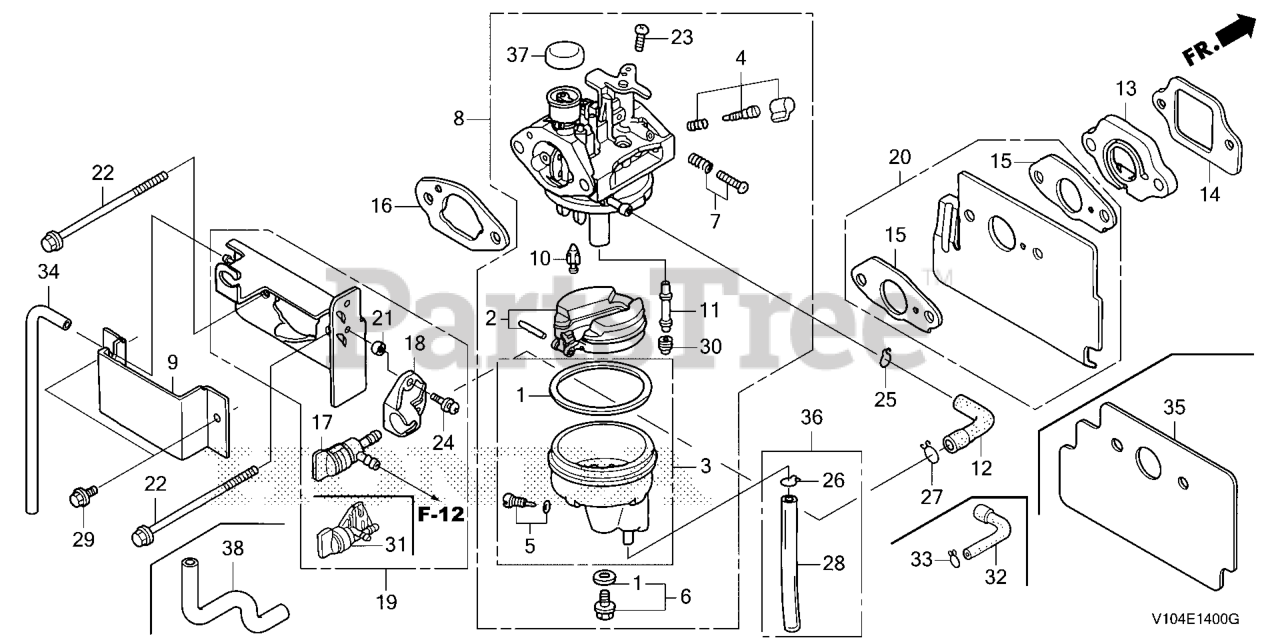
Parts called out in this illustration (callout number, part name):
1	GASKET SET
2	FLOAT SET
3	CHAMBER SET, FLOAT
5	SCREW SET, DRAIN (ADVENTURE GREEN) (CARBURETOR NO.)
6	SCREW SET B
6	SCREW SET
8	CARBURETOR ASSY. (BB70B A)
8	CARBURETOR ASSY. (BB70B C)
9	GUARD, CARBURETOR
10	VALVE, FLOAT (CARBURETOR NO.)
11	NOZZLE, MAIN
11	NOZZLE, MAIN (CARBURETOR NO.)
13	INSULATOR, CARBURETOR
14	GASKET, INSULATOR
16	GASKET, CARBURETOR (Honda Code 5580253). (CHOKE SIDE)
19	STAY ASSY., PETCOCK
21	COLLAR, FR. TURN SIGNAL
22	BOLT, FLANGE (6X79) (CT200)
23	SCREW, PAN (5X6)
24	SCREW-WASHER (5X10)
25	CLIP, TUBE (D8.5)
26	CLIP, TUBE (B6.5)
29	BOLT, FLANGE (6X8)
29	BOLT, FLANGE (6X10)
30	JET, MAIN (#72) Use from Engine SN 6185281.
30	JET, MAIN (#75)
30	JET, MAIN (#78)
30	JET, MAIN (#80)
31	PETCOCK ASSY.
32	TUBE, FUEL (FKM)
32	TUBE(FKM),FUEL
33	CLIP, TUBE (D8)
34	TUBE, AIR VENT
35	GUIDE, AIR
36	TUBE ASSY., DRAIN
37	CAP, CHOKE LEVER DUST
38	TUBE, BREATHER
